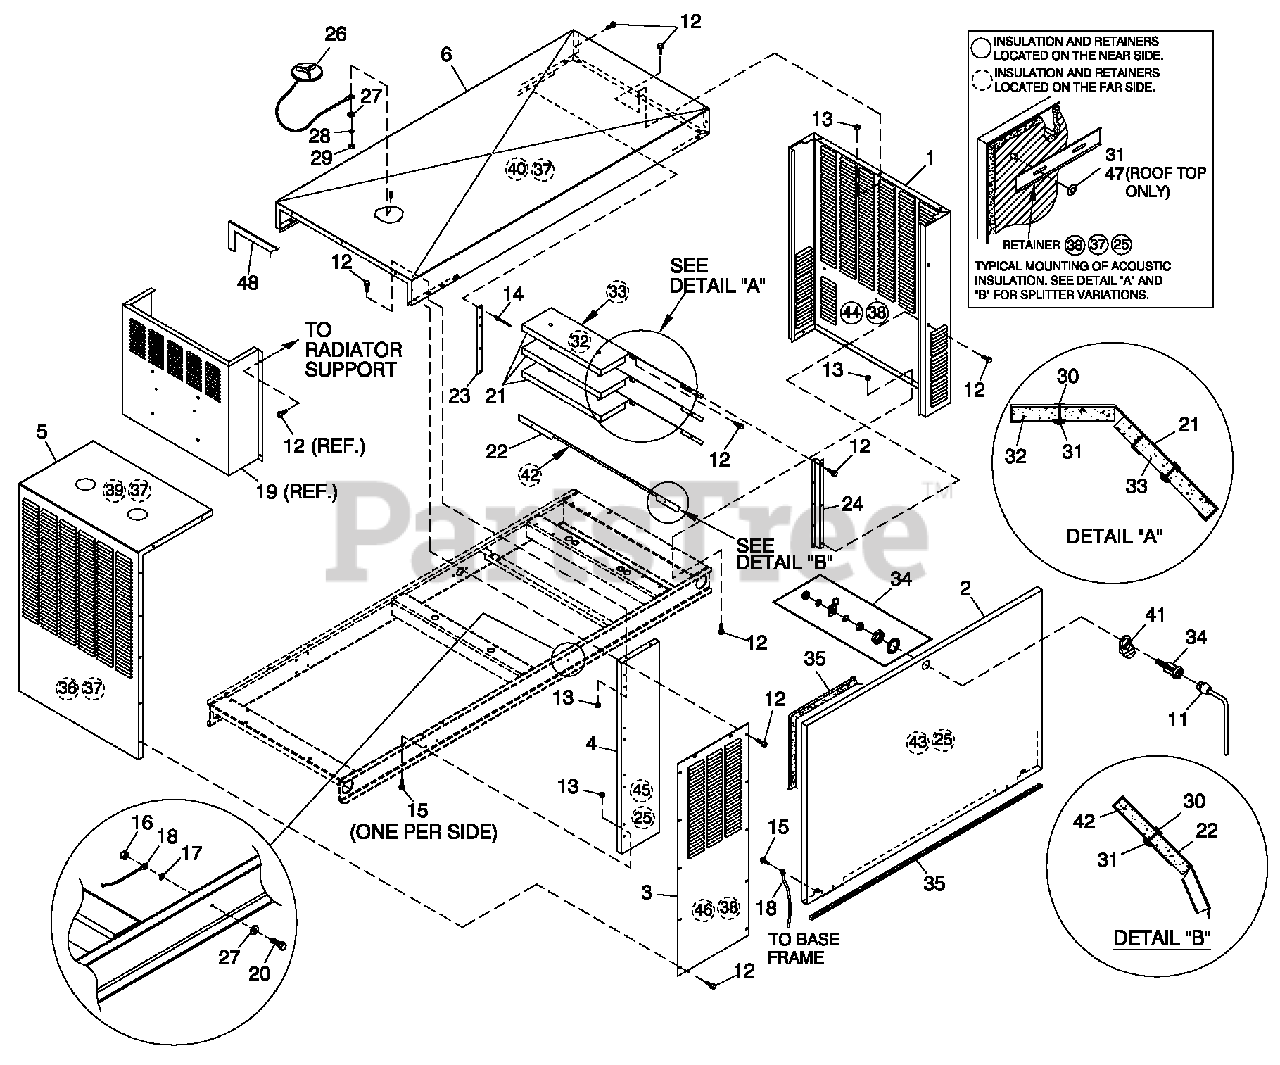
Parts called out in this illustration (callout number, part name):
1	MFLR 7" X 9" (2) 2" IN/2.5" OUT
2	WASHER FLAT 1/4-M6 ZINC
3	RAIN CAP ALUM FOR 2 1/2" PIPE
4	MUFFLER BRACKET STIFFENER
5	MUFFLER STRAP
6	BOLT U 3/8-16X2.62
7	EXHAUST BLANKET 850MM (C4)
8	NUT HEX 3/8-16 SSTL
9	PIPE EXH MANIFOLD RH
10	PIPE EXH MANIFOLD LH
11	GASKET EXHAUST RING
12	WASHER LOCK 3/8 SS
13	SCREW HHC 3/8-16 X 2 SS FTH
14	EXHAUST FLANGE 2" PIPE
15	GLASS PACK 23.5" LG 2.5" IN/OUT
16	WASHER LOCK M6-1/4
17	SCREW THF M6-1 X 16 N WA Z/JS
18	HEAT SHIELD EXHAUST STACK
19	CAP HEAT SHIELD EXHAUST STACK
20	BOLT U 5/16-18X2.25
21	NUT HEX 5/16-24 STEEL
22	WASHER LOCK M8-5/16
23	WASHER FLAT 3/8 SS
24	EXHAUST OUTLET PIPE CPL
25	BOLT U 3/8-16X2.62
26	PIPE EXHAUST ELBOW C4
27	SCREW HHC M6-1.0 X 35 G8.8 BLK
28	NUT HEX M6 X 1.0 G8 YEL CHR
29	MUFFLER STRAP UPPER/LOWER
